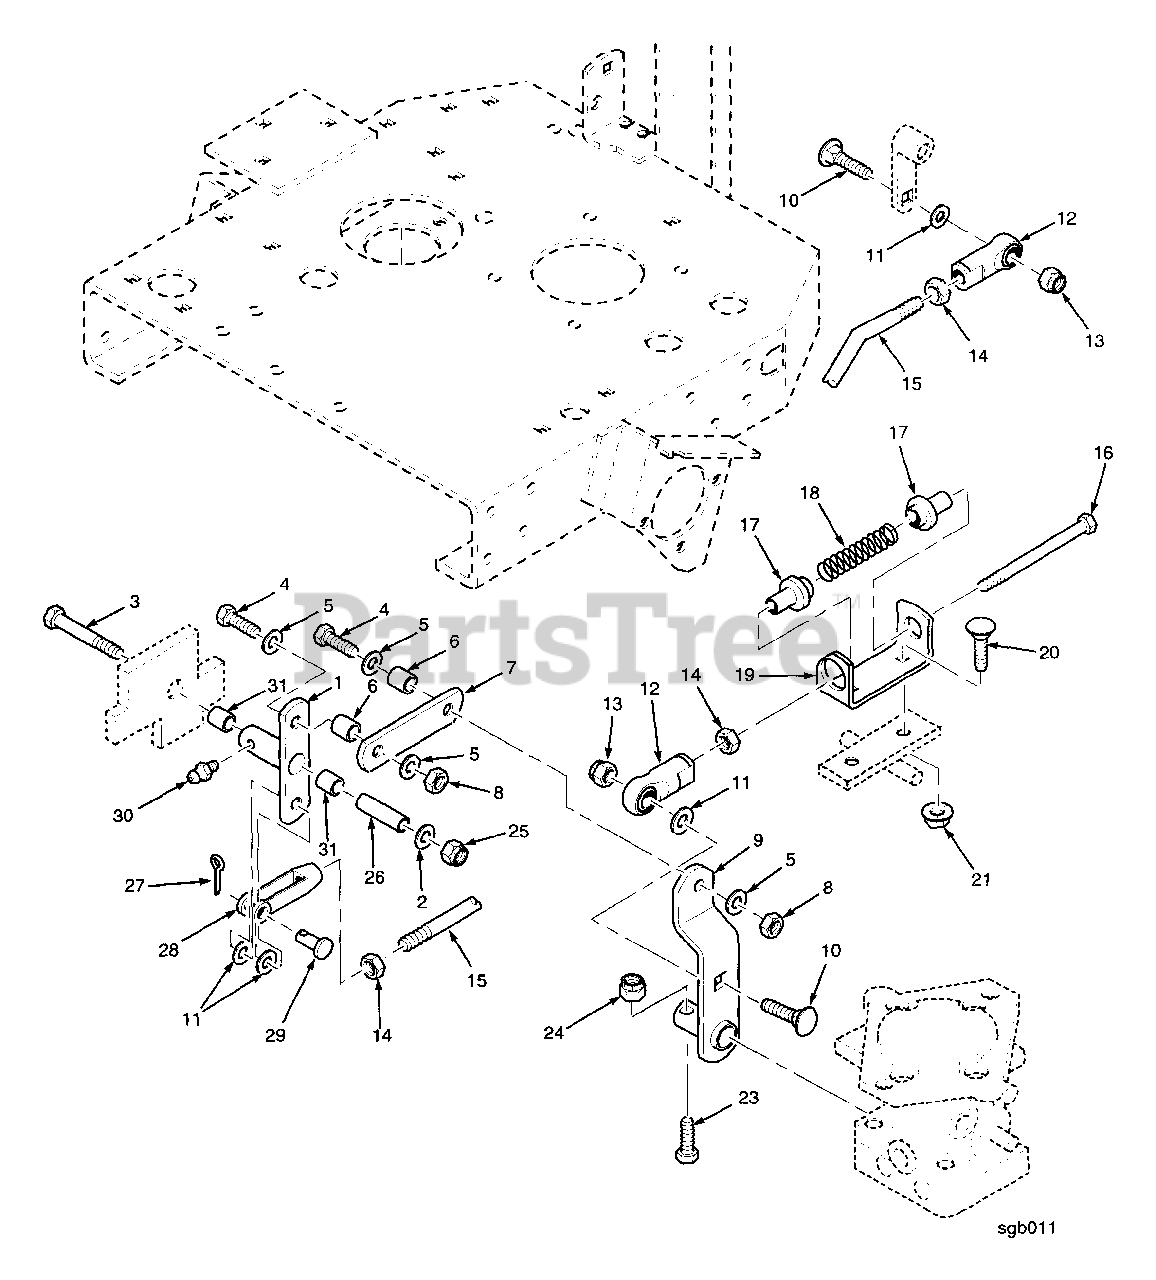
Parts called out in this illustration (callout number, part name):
1	Control Linkage, Bellcrank
2	Flatwasher, 5/16 (.375 x.875 x.083)
3	Bolt, Hex Head 5/16-18 x 2-3/4"
4	Bolt, Hex Head 3/8-16 x 1"
5	Flatwasher, 3/8 (.406 x.812 x.065)
6	Sleeve, Pump Control Link
7	Link, Speed Control
8	Hex Locknut, 3/8-16
9	Control Arm, Pump
10	Carriage Bolt, RH SH SQNK 3/8-16 x 1-1/2"
11	Flatwasher, 3/8 (.391 x .938 x .105)
12	Rod End, RH Female THD 3/8-24
13	Hex Locknut, Elastic Stop 3/8-16
14	Hex Nut, 3/8-24
15	Control Rod
16	Bolt Hex Head, 3/8-24 x 6-3/4"
17	Bushing, Spring Keeper
18	Spring, Neutral Return
19	Retainer, Neutral Spring
20	Carriage Bolt, 5/16-18 x 1"
21	Serr. Fl. Hex Nut 5/16-18
23	Bolt, Hex Head 1/4-20 x 1-1/4"
24	Hex Locknut, Elastic Stop 1/4-20
25	Hex Locknut, Elastic Stop 5/16-18
26	Sleeve, Control Arm
27	Cotter Pin, 3/32 x .75"
28	Clevis, Pump Control
29	Pin, Clevis 3/8"
30	Greese Fitting, 1/4-28 Self Tap
31	Bushing, Bronze
